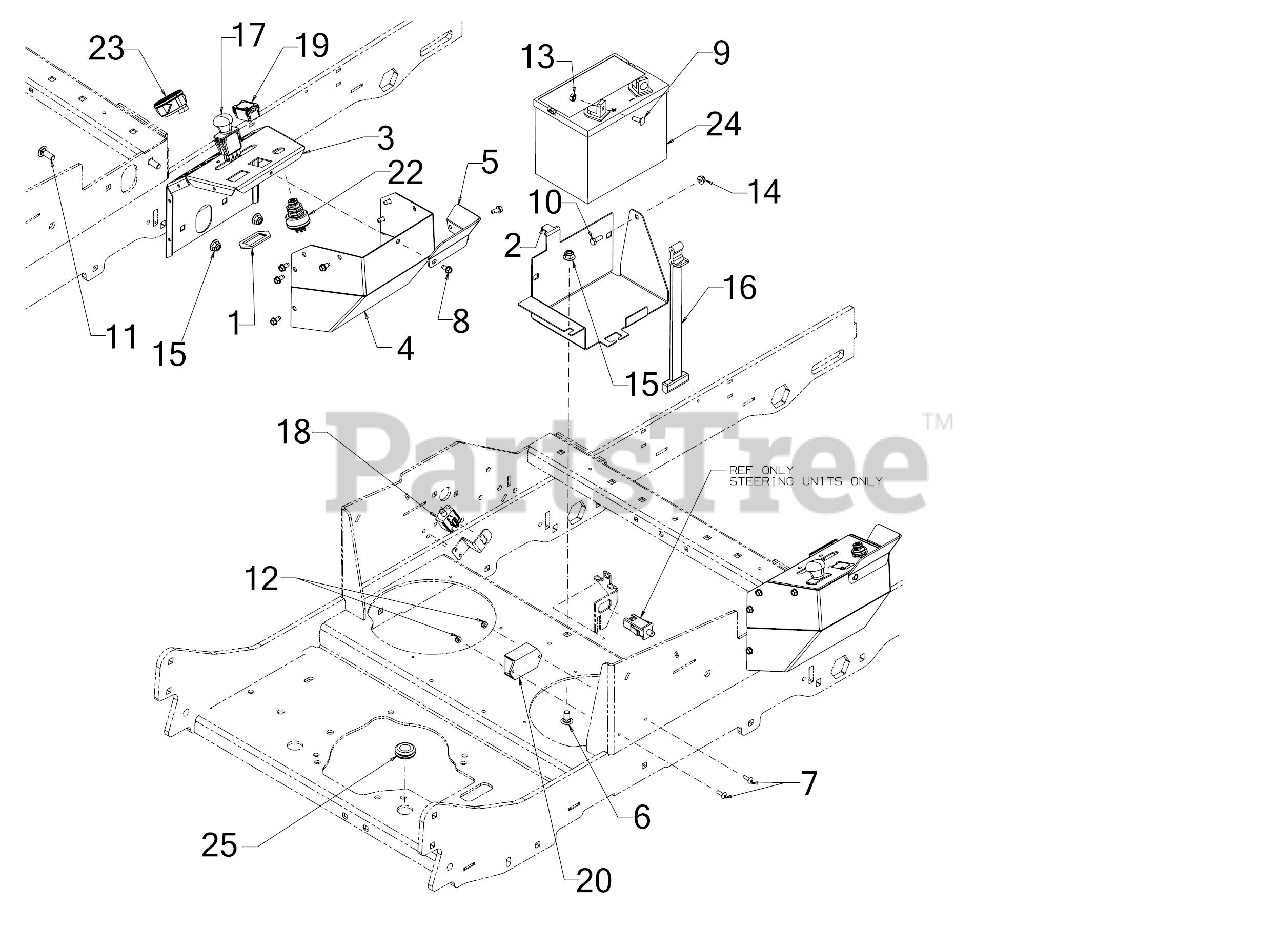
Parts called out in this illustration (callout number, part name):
1	BRACKET-PTO SWITCH
2	BATTERY MOUNTING BRACKET
5	THROTTLE DEFLECTOR
6	CARRIAGE BOLT 3/8-16 x .750 GR5
7	SCREW #10-24 x .62
8	SCREW 1/4-20 X.500
9	SCREW 1/4-20 x .75 GR5
10	SCREW 1/4-20X.75 GR5
11	CARRIAGE BOLT 3/8-16 x 1.00 GR5
13	SEMS NUT 1/4-20
14	FLANGE LOCK NUT
16	BATTERY RETAINER STRAP
17	ELECTRIC PTO SWITCH
18	3 POLE SWITCH ( NC-NO-NO)
20	CONTROL PANEL
22	KEY SWITCH (3 POSITION)
23	DUAL FUEL GAUGE
25	RUBBER GROMMET
